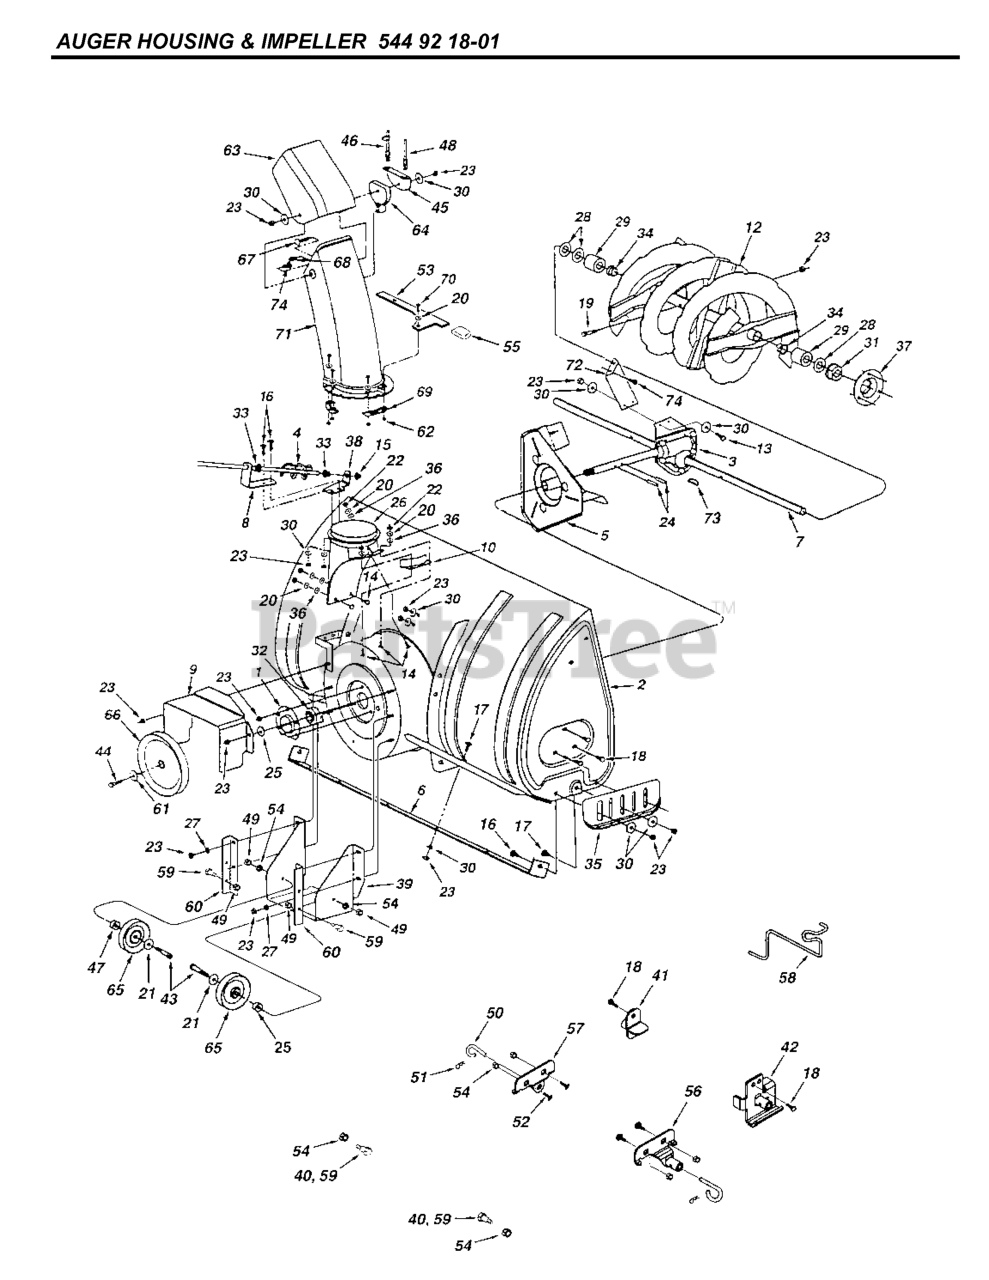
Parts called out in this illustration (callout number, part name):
3	GEAR BOX 71464
9	COVER 24816
17	RP BOLT 5/16-18 X3/4 ZN/YEL GR
20	WASHER - M6
21	WASHER
25	BUSHING 750-0437
30	WASHER BRB 8.4X17
32	BALL BEARING
33	BUSHING 741-0475
39	IDLER BRACKET 24281
40	BOLT 49933
41	BRACKET 65367
42	BRACKET 65450
47	SPACER 711-0242
52	BOLT 43350
53	BRACKET 24394
55	PLASTIC CAP 1643-60
56	BRACKET 64452
57	BRACKET 64451
58	BELT KEEPER 47043
59	BOLT 48106
60	BRACKET 24466
63	CHUTE 731-0921
64	CABLE GUIDE
65	PULLEY 47044
66	PULLEY 47026
74	BOLT.FIN.HEX.5/16-18X3/4
